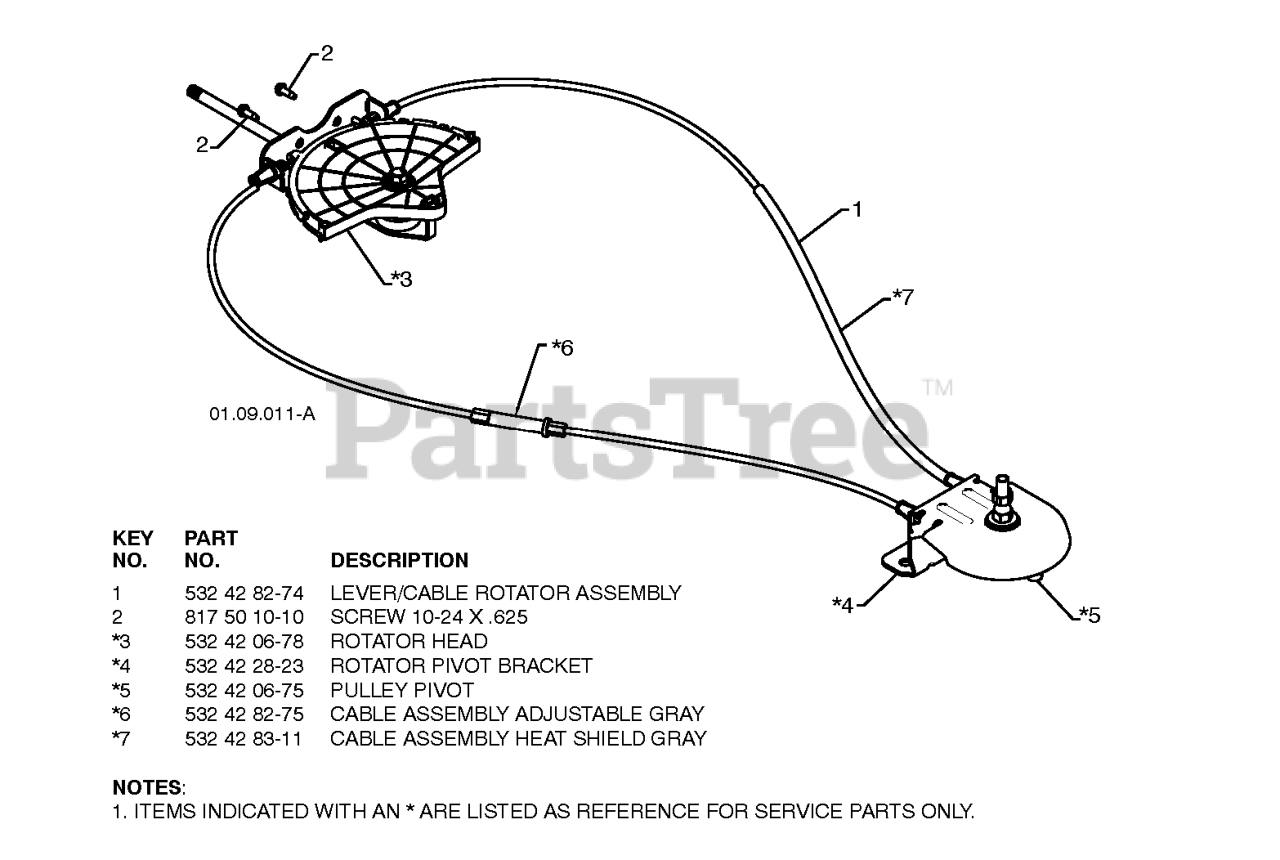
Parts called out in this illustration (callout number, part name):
1	RB LEVER.CABLE.ASM.ROTATR.PLTD
2	SCREW #10-24 X 5/8
3	CHUTE.ROT.HEAD.SERVICE
4	SNOW.PIVOT.BRKT.GRY.SERVICE
5	SNOW.PIVOT.PULLY
6	SNOW.CABLE.ASM.ADJUSTABLE.GRAY
7	SNOW.CABLE.ASM.SERVICE
